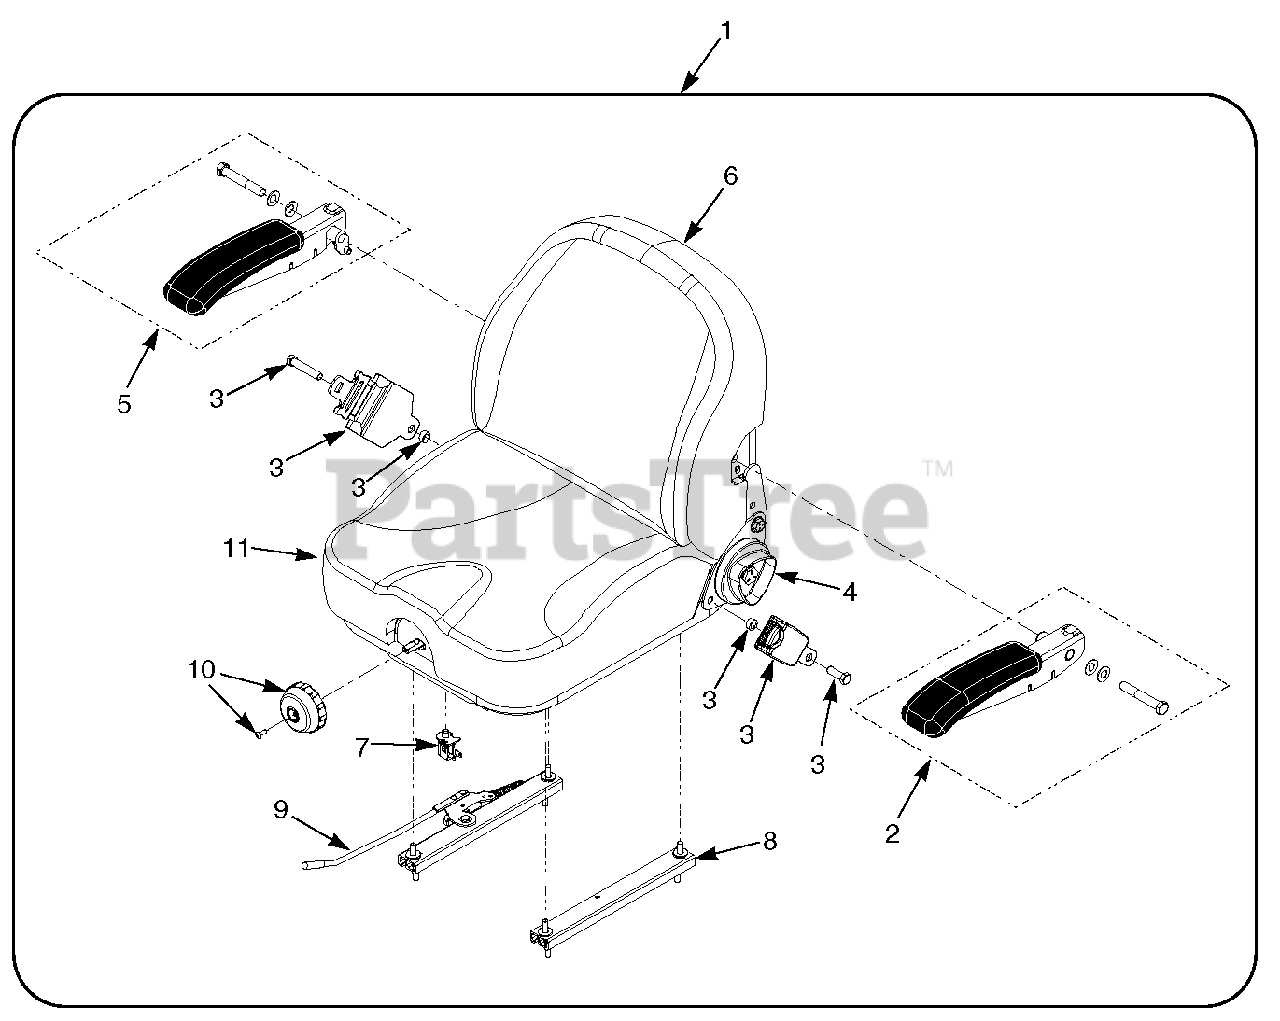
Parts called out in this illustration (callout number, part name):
1	Seat Assembly
2	Armrest Kit, LH
3	Seat Belt Kit
4	Knob Kit, Recliner
5	Armrest Kit, RH
6	Back Cover
7	Switch, N/O
8	Track Kit
9	Handle, Seat Track
10	Knob Kit, Weight Adjust
11	Cover, Seat Cushion
